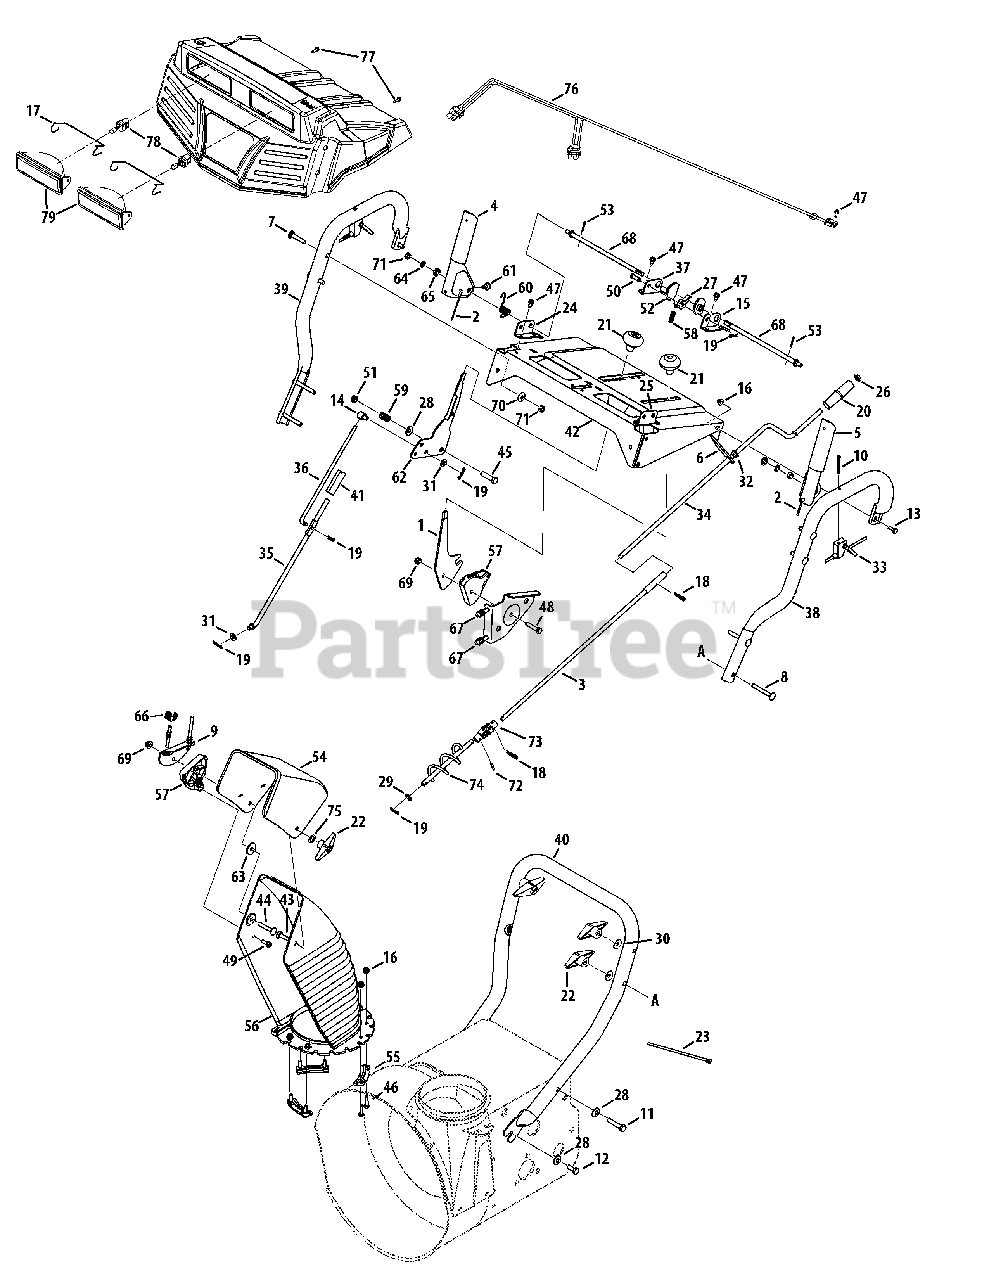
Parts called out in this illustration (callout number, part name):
1	Chute Tilt Handle
2	Cable Ass’y (Auger/Drive)
4	Engage Handle RH Black
5	Engagement Handle LH Black
6	Upper Chute Crank Support
7	Carriage Bolt 5/16-18 x 1.75" Lg.
8	Carriage Bolt 5/16-18 X 2.50
10	Screw, #10-24 x 1.75
11	Hex Screw 3/8-16 x 2.0
12	Hex TT Screw 3/8-16 x .75
13	Hex Cap Bolt 1/4-20 x .75" Lg.
14	Adjustment Ferrule
15	LH Handle Support Brkt. 5/8"
16	Hex L-Flanged Nut 1/4-20 Gr. F Nylon
17	Retainer
18	Internal Cotter Pin
19	Int. Cotter Pin .072 x 1.13" Lg.
20	Knob 1.0 x 3.2
21	Shift Knob
22	Knob
23	Cable Tie
24	RH Handle Support Brkt. 3/8"
26	Push Nut 3/8" Rod
27	Cam Lock Pawl
28	Cupped Washer .375 ID x .870 OD x .063
29	Flat Washer .406" I.D. x .75" O.D.
30	Cupped Washer .345 ID x .88 OD x .06
31	Flat Washer .34 ID x .688 OD x .065
32	Plastic Bushing .380 ID
33	Steering Trigger
34	Upper Chute Crank Assembly
35	Lower Shift Rod
36	Upper Shift Rod
37	RH Handle Support Brkt. 5/8"
38	Upper Handle LH
39	Upper Handle RH
40	Lower Handle
41	Connector - Shift Rod
42	Handle Panel Support Ass’y
43	Carriage Bolt 5/16-18 x 1.00" Lg
44	Carriage Bolt 5/16-18 x 1.75" Lg.
45	Hex Scr 3/8-24 x 1.50
46	Screw 1/4-20 x 1.0
47	Hex Wash S-Tapp Scr 1/4-20 x .50
48	Hex Bolt 5/16-18 x 1,50" Lg.
49	Hex Tapp Scr 1/4 x .75" Lg.
50	Clevis Pin .31 Dia. x 1.0" Lg.
51	Hex Nut 3/8-16 Gr. 5 Nylon
52	Cam Handle Lock
53	Cotter Pin 3/32 x .75
54	Upper Chute
55	Chute Flange Keeper
56	Lower Chute
57	Cable Guide
58	Compression Spring .62 OD x 6.12" Lg.
59	Compression Spring .38 ID x .88 Lg
60	Torsion Spring
61	Rubber Bumper
62	Shift Lever
63	Flat Washer .344 ID x 1.125 OD x .125
64	L-Wash 5/16 ID
65	Flat Washer (special) .350 sq. x .72 x .134
66	Cable Clip
67	Chute Control Cable w/clip
68	Cam Rod
69	Hex L-Flanged Nut 5/16-18 Gr. F Nylon
70	Flat Washer .349 ID x .879 OD x .063
71	Hex Patch L-Nut 5/16-18
72	Spiral Pin .156 Diam x .80" Lg.
73	Joint Block Ass’y
74	Chute Crank Assembly
75	Flat Washer .349 ID x .879 OD x .063
76	Wire Harness
77	Hex Tapp Wash Hd. Scr. #10 x 5/8
78	Bulb #890, 12 V, 27 Watt
79	Headlight Housing
80	Black Handle Panel
